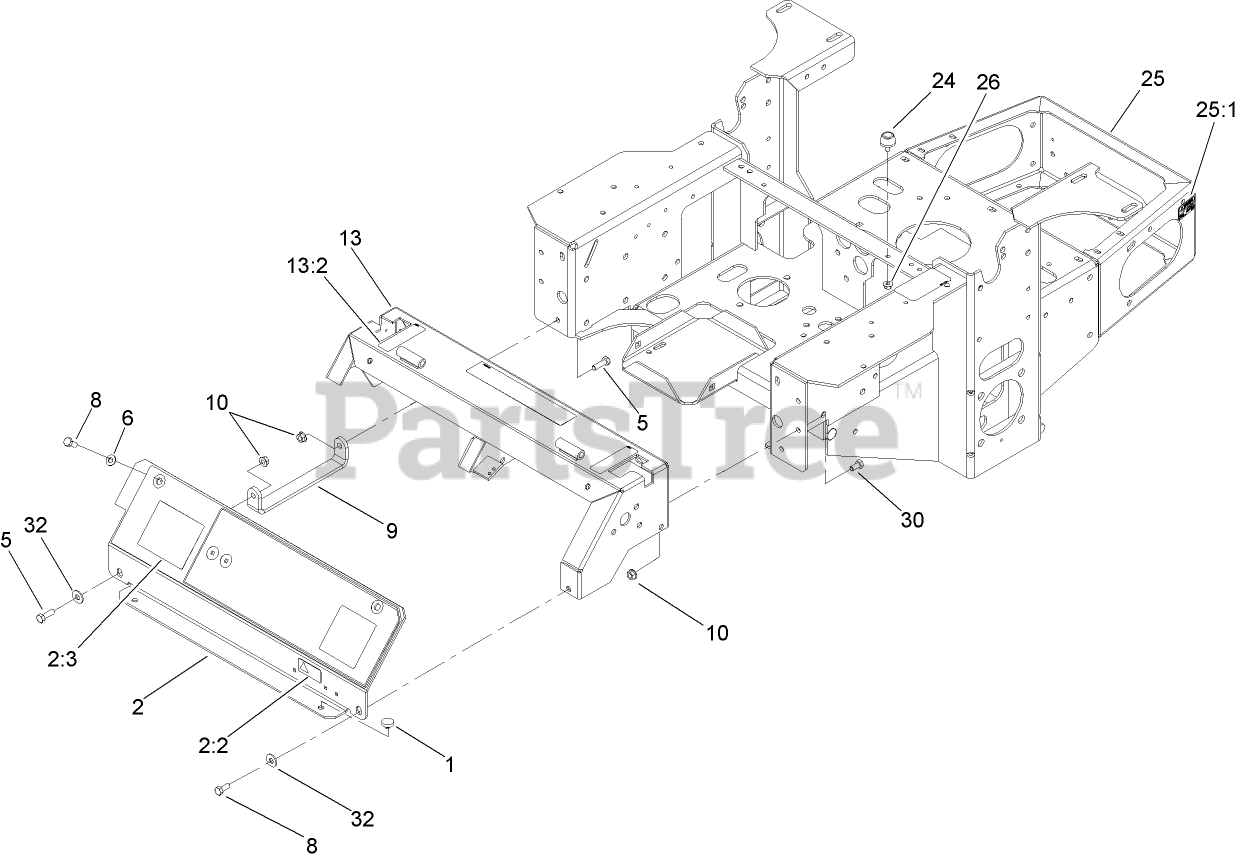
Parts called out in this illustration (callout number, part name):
1	BUMPER
2	PANEL ASM
2:2	DECAL-PROTECTION, EAR
2:3	DECAL-COVER, PANEL
5	SCREW-HH
6	WASHER-PLAIN
8	SCREW-HH
9	BRACKET-PANEL, INSTRUMENT
10	NUT-HF
13	CONSOLE ASM
13:2	DECAL-WARNING
24	BUMPER-RUBBER
25	MAIN FRAME ASM
25:1	DECAL-SURFACE, HOT
26	NUT-HF
30	SCREW-HH
32	WASHER-FLAT
